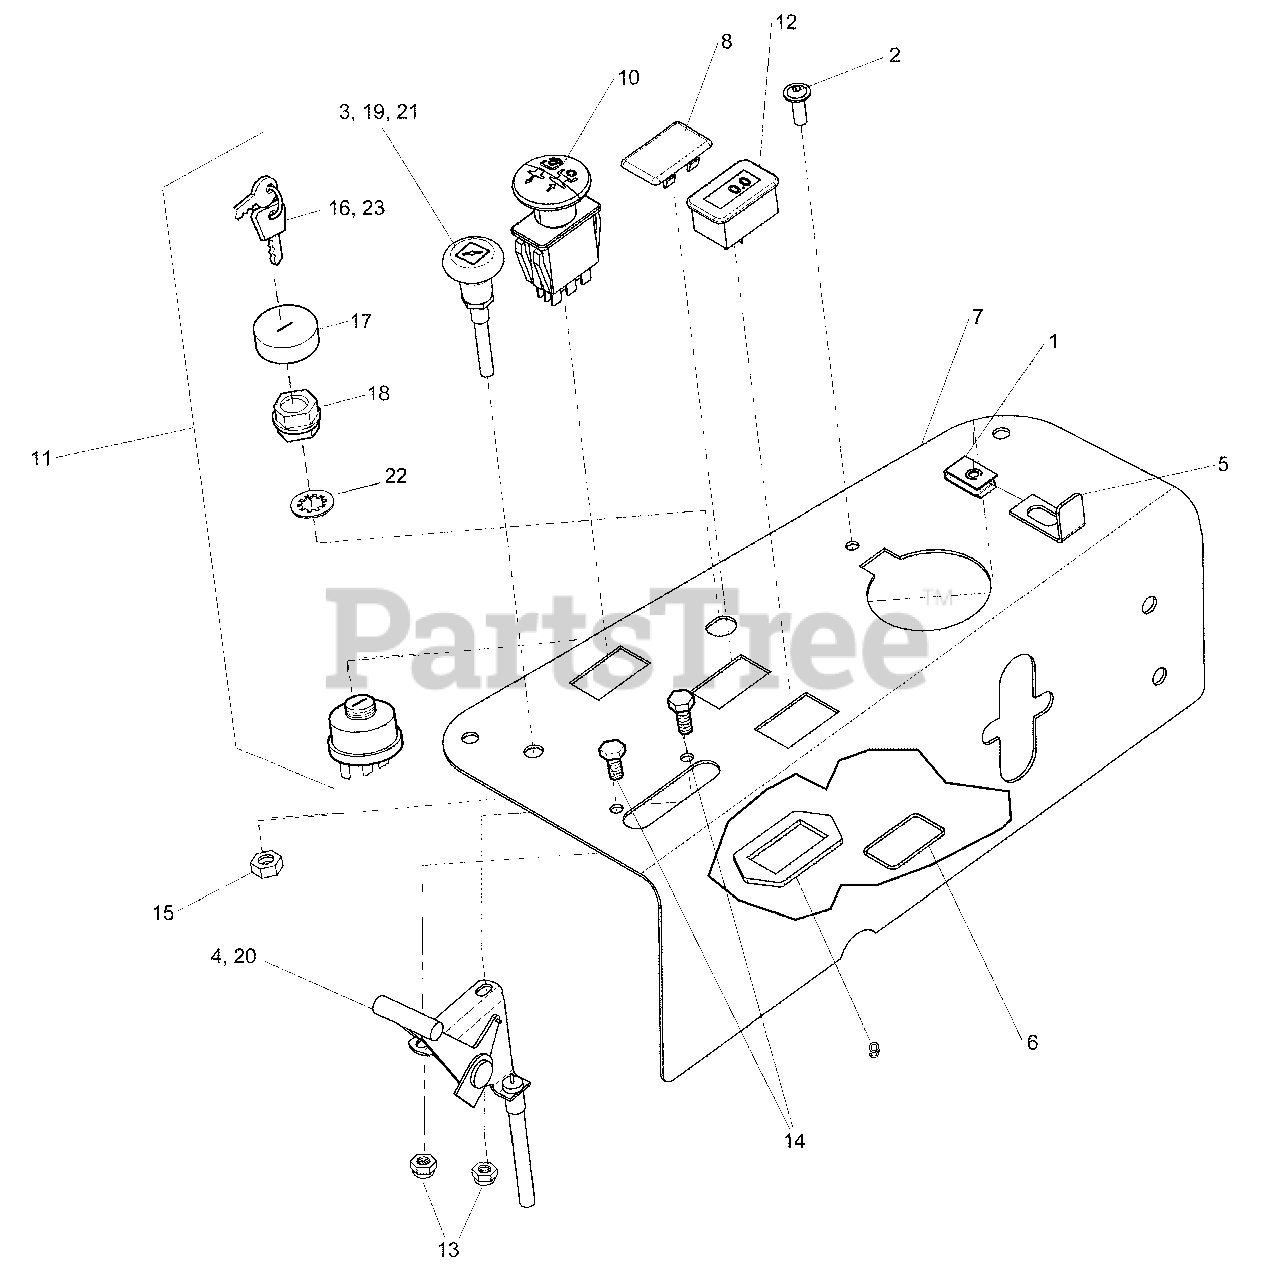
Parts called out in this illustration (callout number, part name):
1	BODY CLIP, 1/4-20 X .500 DEEP
2	SCREW, ALLEN HEAD, 1/4-20 X 3/4"
3	CABLE, CHOKE CONTROL, 51 (Z)
4	CABLE, THROTTLE CONTROL, 36"
5	BRACKET, LOCK
6	O-RING, 7/8" ID X 1/16" W
7	PLATE, CONTROL TANK COVER
8	HOLE, PLUG DASH
9	RING, SWITCH RETAINER, PTO
10	SWITCH, BLADE ENGAGEMENT
11	SWITCH ASMY-IGNITION INDAK NO KEYS/HKWR
12	HOUR METER, W/ SUPRESSOR
13	NUT, Hex Nylon Lock, 1/4-20
14	BOLT, 1/4-20 x 3/4
15	NUT, 3/8-24 HEX JAM
16	KEYS, BLISTER PK KIDS+MWRS DON'T MIX, DOM, USA MODELS ONLY
17	COVER, SWITCH
18	NUT-HEX FLANGE 5/8-32 IGN SW DIE CAST
19	CABLE, CHOKE CONTROL, 43.5"
20	CABLE, THROTTLE CONTROL, 27.5"
21	CABLE, CHOKE CONTROL, 35.25"
22	LOCKWASHER-INTERNAL TOOTH, .625 THIN BLK
23	KEYS, BLISTER PK KIDS+MWRS DON'T MIX, EXP, CE MODELS ONLY
